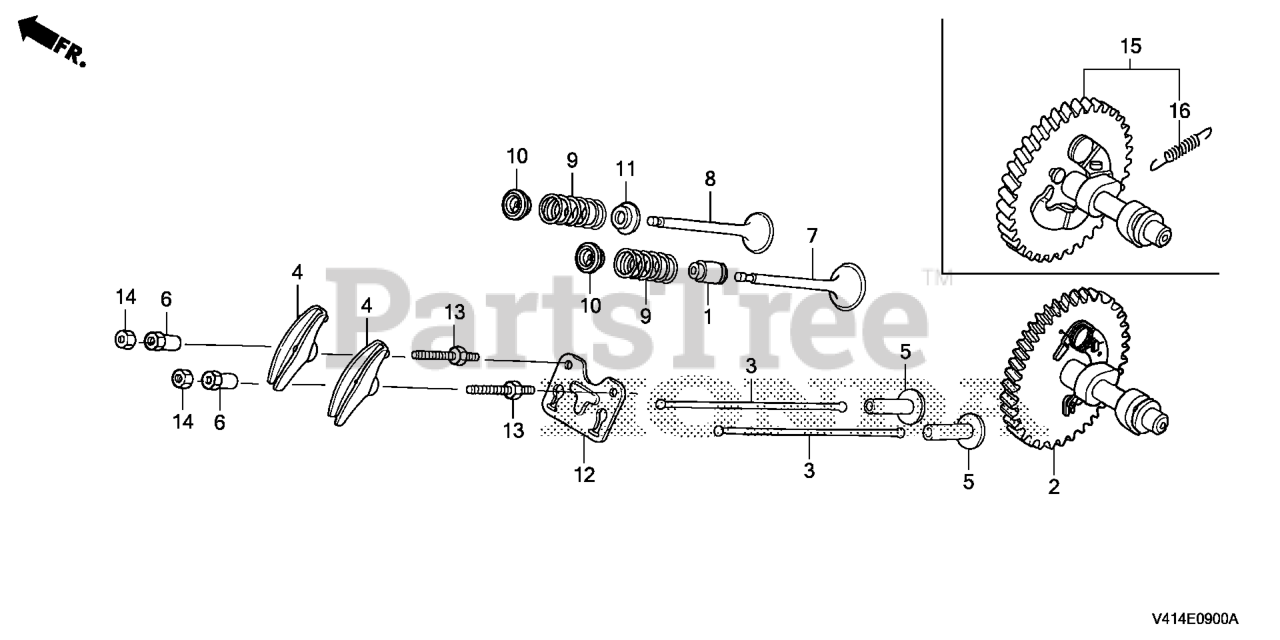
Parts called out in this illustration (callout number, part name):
1	SEAL, VALVE STEM
2	CAMSHAFT (STD)
2	CAMSHAFT COMP (STD)
4	ARM, VALVE ROCKER
5	LIFTER, VALVE
6	PIVOT, ROCKER ARM
7	VALVE, IN.
8	VALVE, EX.
9	SPRING, VALVE
10	RETAINER, IN. VALVE SPRING (EXHAUST SIDE)
11	SEAT, VALVE SPRING
12	GUIDE, PUSH ROD
13	BOLT, PIVOT (8MM)
14	NUT, PIVOT ADJ.
